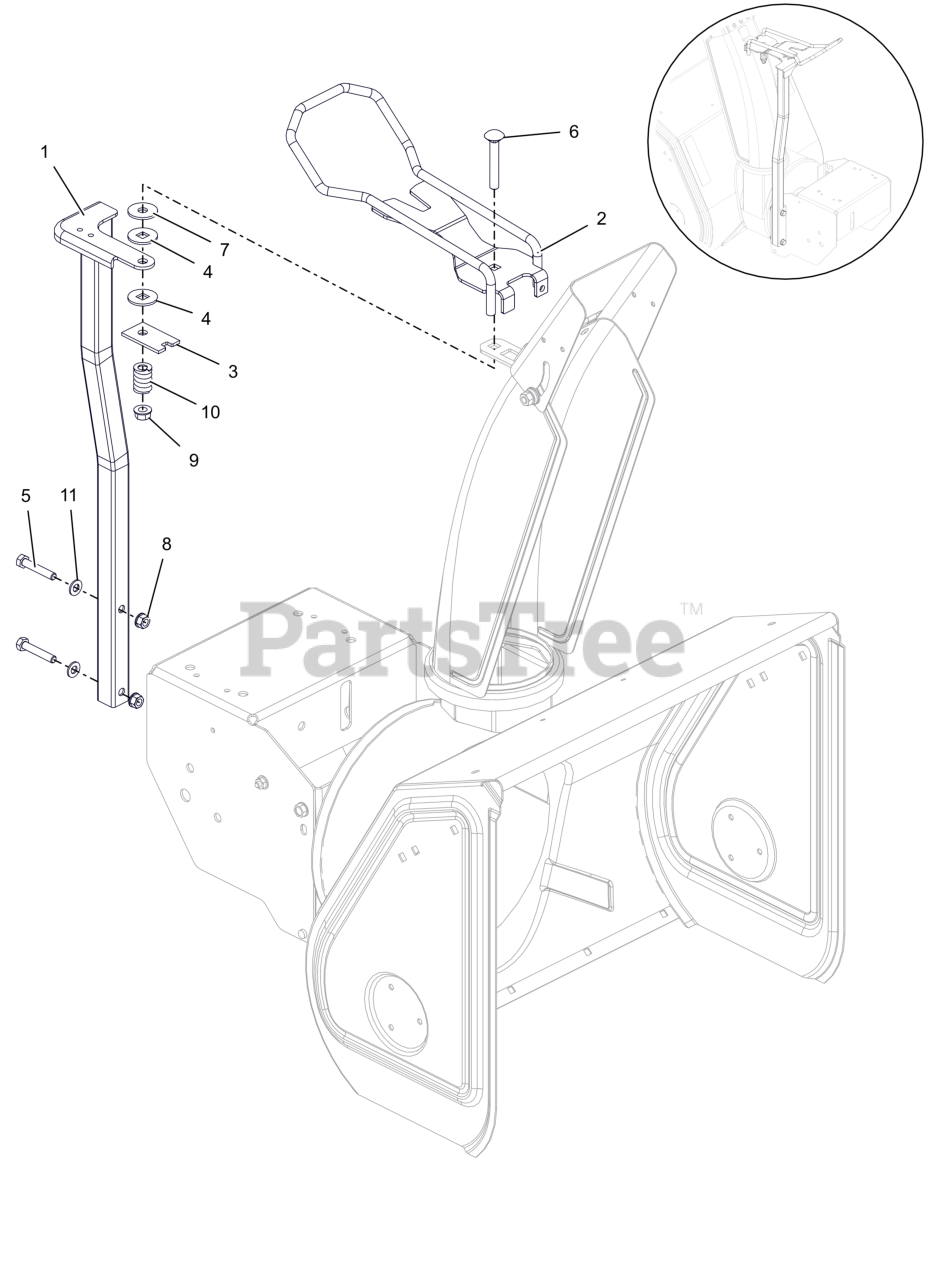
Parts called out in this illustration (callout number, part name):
1	WLDMT, PEDESTAL CHUTE MANUAL (BLACK)
2	WLDMT, CHUTE ROTATION LEVER (BLACK)
3	PLATE, FRICTION
4	FRICTION WASHER
5	BLT, HEX .31-18X1.75 G5 ZCC
6	BLT,RHSN .38-16X2.50 G5 ZCC
7	WSHR FL STL .406X1.25X.10ZC120
8	NUT,LK-CTR-FLG .31-18 GF ZCC
9	NUT-LK-CTR-FLG .375-16 GF ZCC
10	SG-COMP .187X.56X1.62
11	WSHR,FLT .344X.688X.065 ZCC
